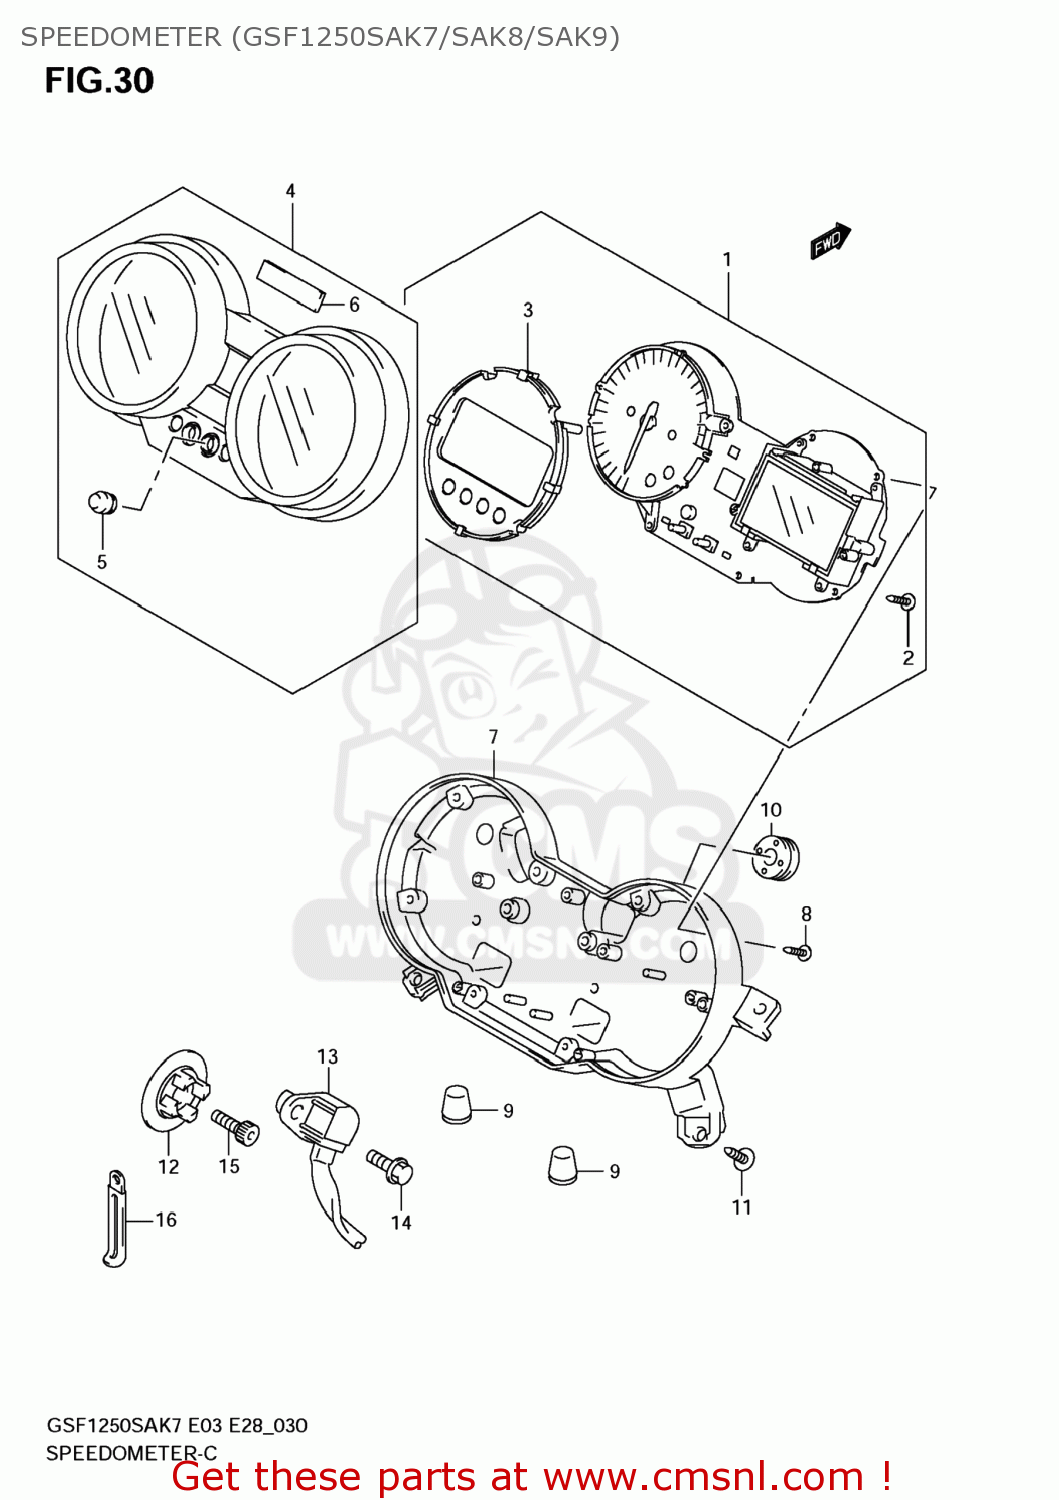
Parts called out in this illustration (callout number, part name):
1	SPEEDOMETER
2	SCREW(3X16)
3	REFLECTOR
4	UPR CASE
5	RUBBER,SWITCH
6	PACKING (NAS)
7	LWR CASE
8	SCREW(3X16)
9	CUSHION,SPEEDOMETER
10	CUSHION
11	SCREW
12	ROTOR,SPEED
13	SENSOR,SPEED
14	BOLT
15	BOLT
16	CLAMP(L:45)
